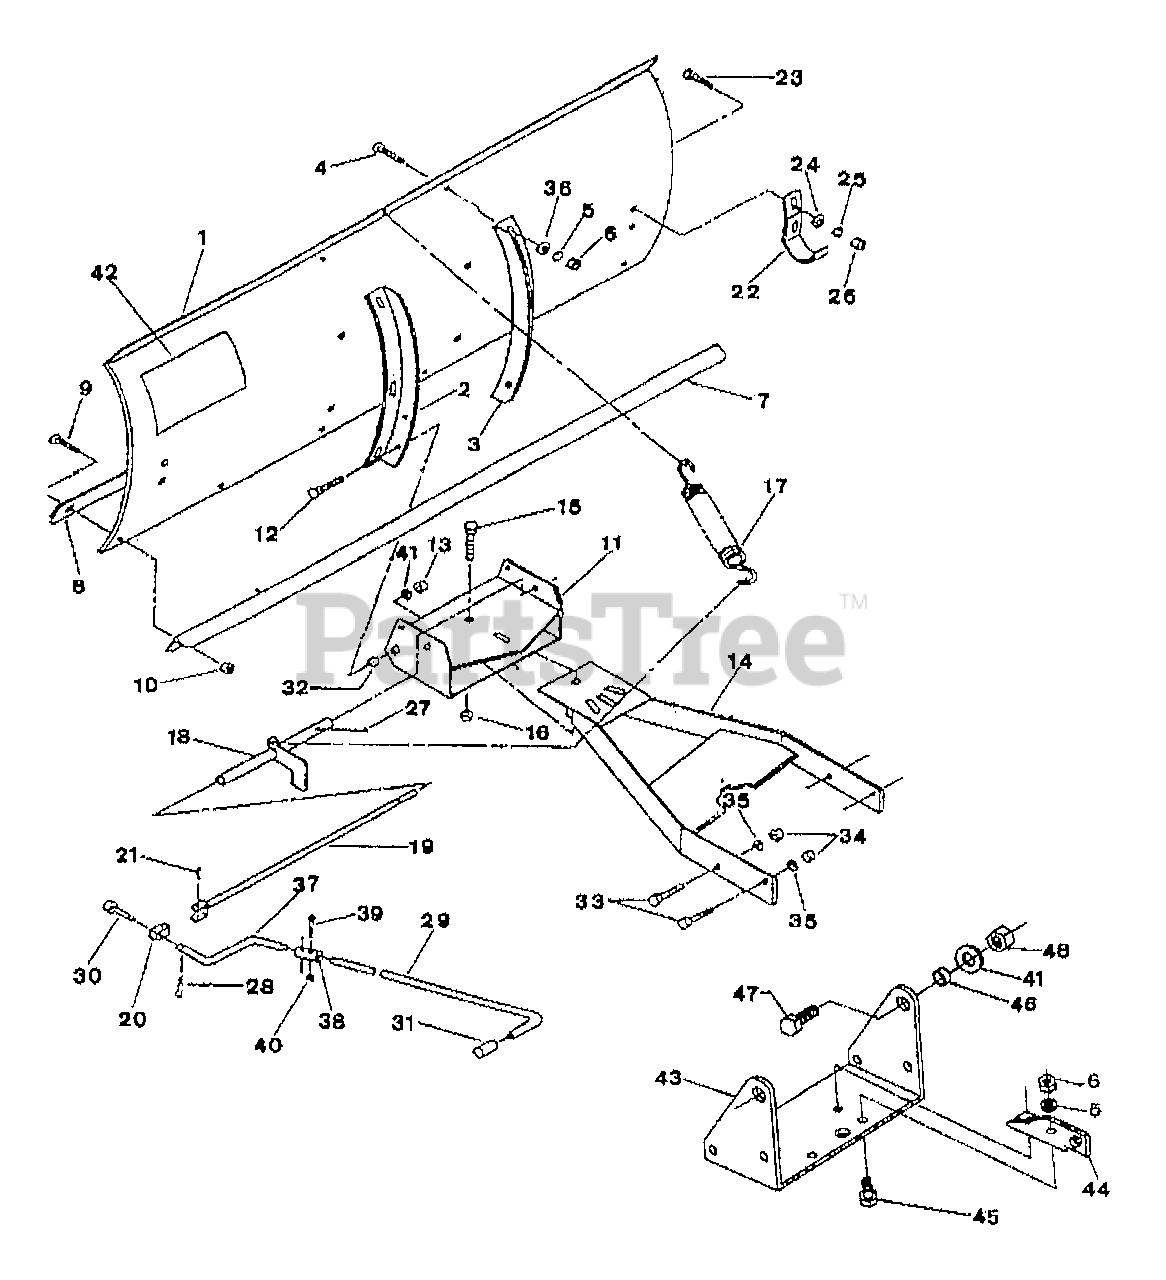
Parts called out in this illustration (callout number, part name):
1	MOLDBOARD 44" {14079}
1	MOLDBOARD 54" {14080}
2	ANGLE-REINFORCEMENT LH
3	ANGLE-REINFORCEMENT RH
4	SCR-CARR 3/8-16X1.00
5	WASHER-LK .375 @ DEPL
6	NUT-HEX 3/8-16 ZP
7	MOLDBOARD REINFORCEMENT (44) {14079}
7	MOLDBOARD REINFORCEMENT (54) {14080}
8	EDGE-CUTTING (44)
8	EDGE-CUTTING (54)
9	SCR-CARR 5/16-18X.75 G2 ZP {14079}
9	SCR-CARR 5/16-18X.75 G2 ZP {14080}
10	NUT-H/LK 5/16-18 {14079}
10	NUT-H/LK 5/16-18 {14080}
11	FEMALE ATTACHMENT
12	BOLT-CARR .500-13X1.50
13	NUT-TOP LOCK 1/2-13 ZP
14	MALE ATTACHMENT
15	SCR-CARR 5/8X4.0
16	NUT-H/LK 5/8-11
17	SPRING
18	LEVER-LOCKING
19	ROD-ANGLE LINKAGE
20	BLOCK
21	PIN-ROLL 1/4 X 1-1/4
22	SHOE-SKID
23	SCR-CARR 5/16-18X1.0 G2 ZP
24	WASHER-FLAT 3/8 SAE
25	WASHER-LK .312 ZP
26	NUT-HEX 5/16-18 ZP
27	PIN-ROLL .188X.75
28	PIN-HITCH .125X2.56 ZP
29	ARM-ANGLE ADJUSTING
30	PIN (SPECIAL)
31	GRIP-HANDLE
32	BUSHING
34	NUT-HH 7/16-14X.375
35	WASHER-LK .438 ZP
36	SCR-HH 3/8-16X1.75 G5 ZP
37	ARM-LOWER ADJ
38	TUBE-UNION
39	HEX. SOCKET CAPSCREW
40	NUT-HT LK 1/4-20
41	WASHER-FLAT 19/32X1 3/16X.
42	DECAL-SAFETY
43	BRACKET-PIVOT
44	BRACKET-PUSH
45	SCR-HH 3/8-16X1.0 G5 ZP
46	SPACER-TUBULAR
47	SCR-HH 1/4-20X1.25 G5 ZP
48	NUT-TOP LOCK 1/2-13 ZP
